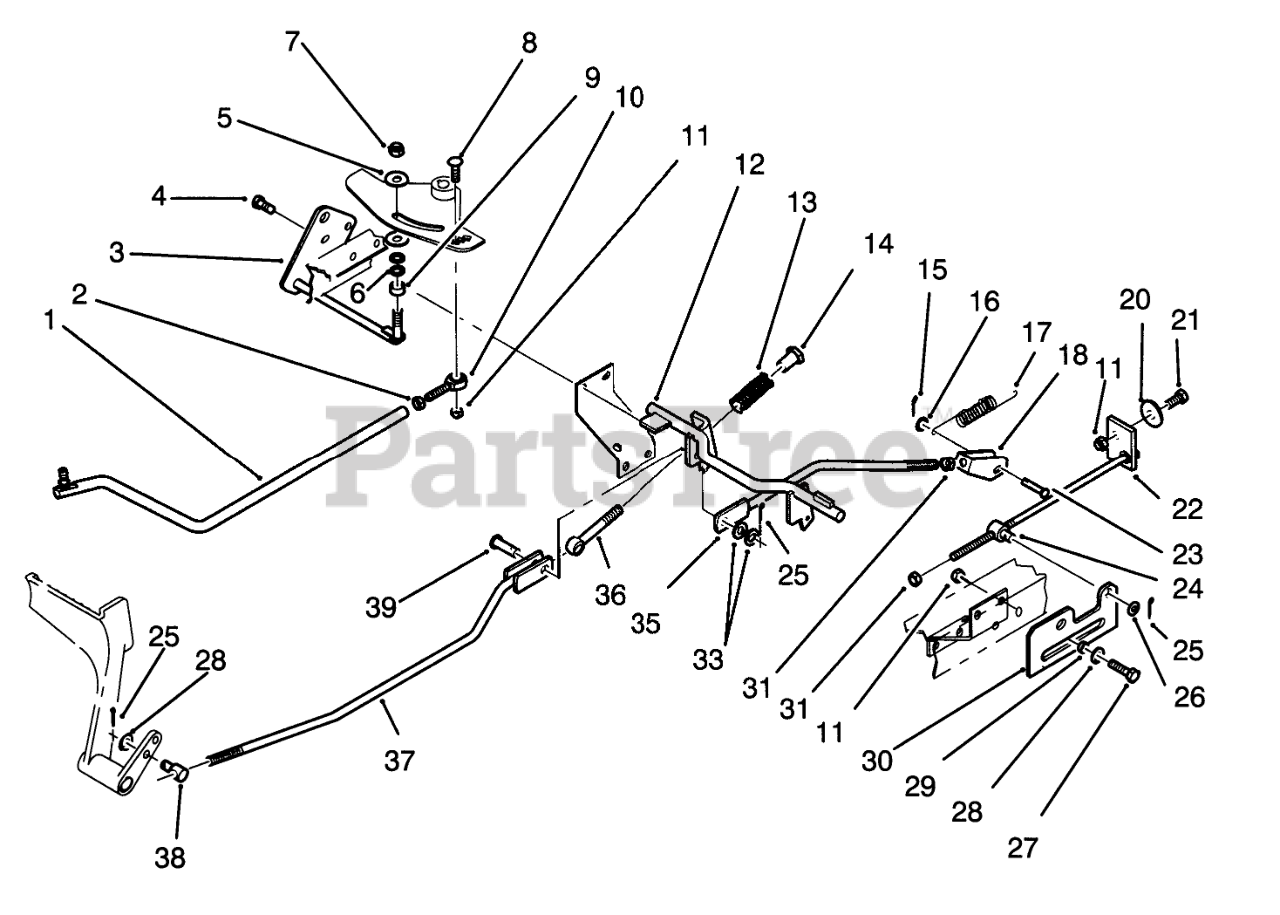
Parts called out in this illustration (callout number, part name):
1	ROD-CONTROL R
2	NUT-JAM
3	WLDMT-ROD R
4	Screw
5	FRICTION WASHER
6	WASHER-SPRING DISC
7	NUT-LOCK, NI
8	Bolt-Carriage
9	SPACER
10	BALL-END
11	NUT-LOCK, NI
12	WLDMT-NEUTRAL SHA R
13	SPRING-COMPRESSION
14	NUT-RETAINER
15	PIN-COTTER
16	WASHER-FLAT
17	SPRING-EXTENSION
18	WLDMT-CLEVIS
20	WASHER
21	SCREW-HH
22	WLDMT-BOLT
24	TRUNNION
25	PIN-COTTER
26	WASHER-PLAIN
27	SCREW-HH
28	WASHER-PLAIN
29	SPACER
30	PLATE R
31	NUT-JAM
33	WASHER-FLAT
35	WLDMT-ROD
36	EYE-BOLT
37	WLDMT-BRAKE ROD
38	TRUNNION
39	CLEVIS PIN
